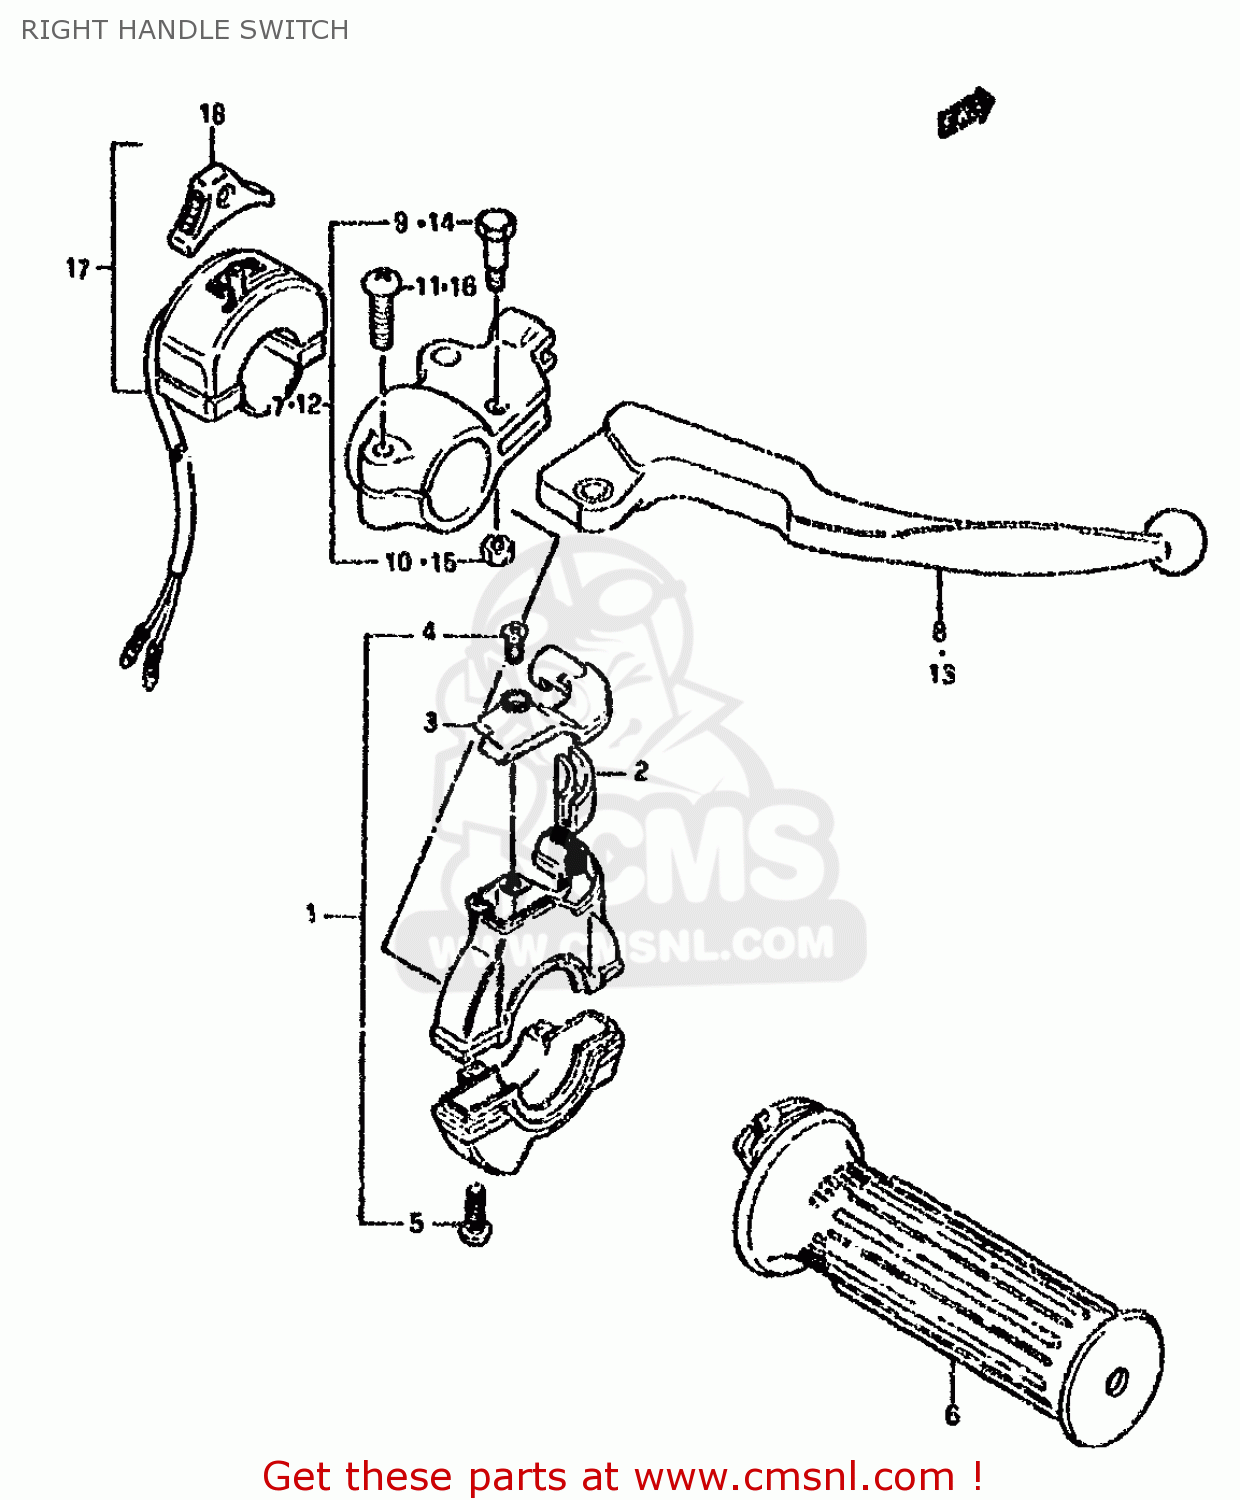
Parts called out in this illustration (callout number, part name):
1	CASE ASSY,THROTTLE
2	GUIDE PIECE,THROTTLE
3	COVER,THROTTLE CASE
4	SCREW,UPPER
5	SCREW
6	GRIP,THROTTLE
7	LEVER ASSY,BRAKE
8	LEVER,BRAKE
9	BOLT,LEVER PIVOT
10	NUT 5MM
11	SCREW
12	LEVER ASSY,BRAKE
13	LEVER,BRAKE
14	SCREW
15	NUT 8MM
16	SCREW
17	SWITCH ASSY,LIGHTING
18	KNOB,LIGHTING & DIMMER
